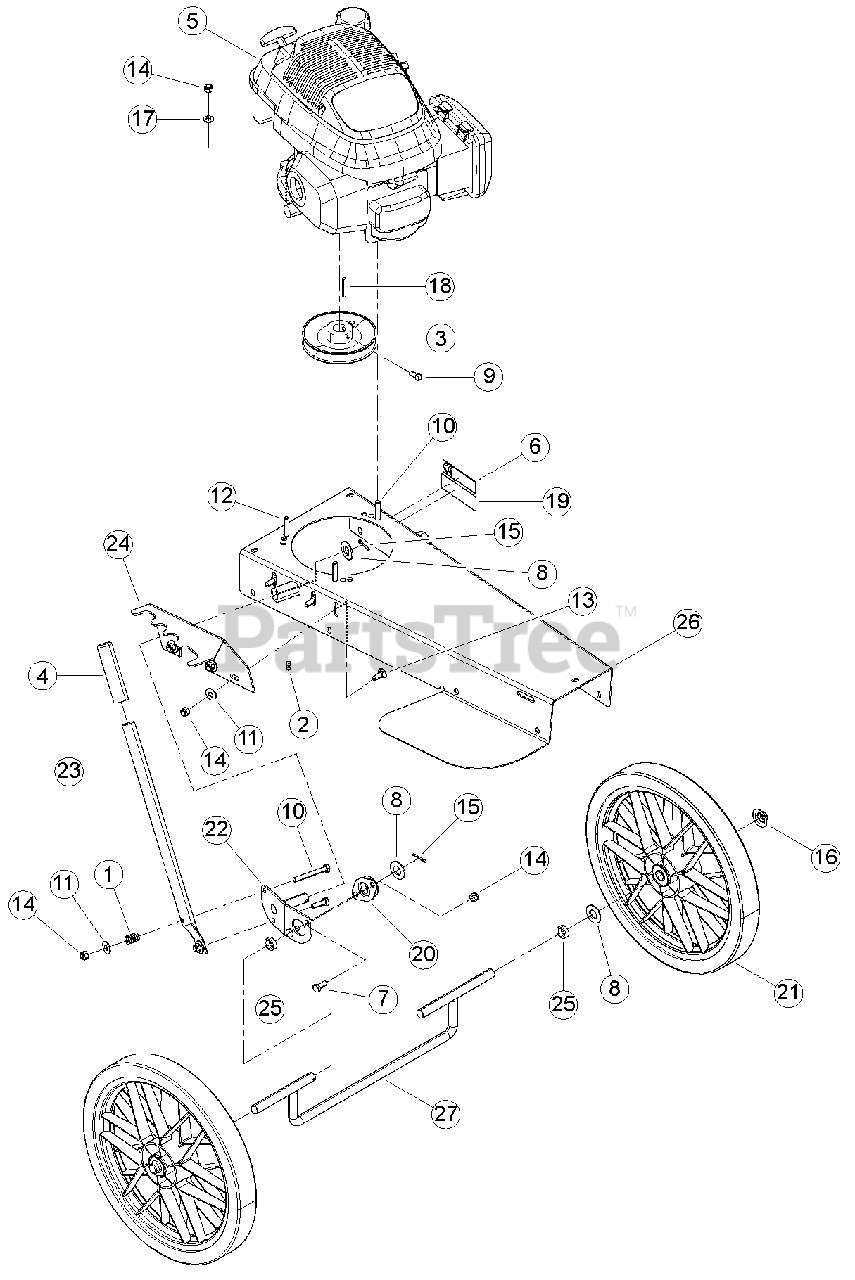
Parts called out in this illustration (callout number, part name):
1	SPRING, HEAVY DUTY COMPRESSION
2	FITTING, 1/4 SELF-TAP GREASE
3	PULLEY, 5.0 X 7/8 AB
4	GRIP, TILT CONTROL
5	ENGINE, 6.5 HP QUANTUM HD 49 STATE (CALIF. EMISSION COMPLIANT) (FOR SERVICE SEE ENGINE OWNER'S MANUAL OR YOUR NEAREST AUTHORIZED HONDA ENGINE DEALER.)
6	DECAL, 6.5 HP TILT INFORMATION
7	BOLT, 5/16 X 3/4 HEX HD GR5 ZP
8	WASHER, 5/8 SAE FLAT ZP
9	SCREW, 5/16-18 X 5/8 SQ HD SET
10	BOLT, 5/16 X 2-1/2 HEX HD GR5 ZP
11	WASHER, 5/16 FLAT ZP
12	BOLT, 5/16 X 1-1/2 HEX HD GR5 ZP
13	BOLT, 5/16 X 7/8 CRG GR5 NC ZP
14	NUT, 5/16 NE NYLOCK ZP
15	PIN, 1/8 X 1.00 COTTER ZP
16	PUSHNUT, 5/8 ZP
17	WASHER, 5/16 SAE FLT ZP
18	KEY, 3/16 SQUARE X 1-1/2 LONG PLAIN
19	DECAL, SERIAL NUMBER
20	BEARING, SIDE FLANGE MOUNT, 5/8
21	WHEEL, 15 INCH TRIMMER (BLACK)
22	WELDMENT, AXLE PIVOT
23	HANDLE, TRIMMER HEIGHT ADJUST
24	PLATE, HANDLE LOCK
25	SPACER, 7/8 X .281
26	WELDMENT, TRIMMER BODY
27	WELDMENT, TRIMMER AXLE
